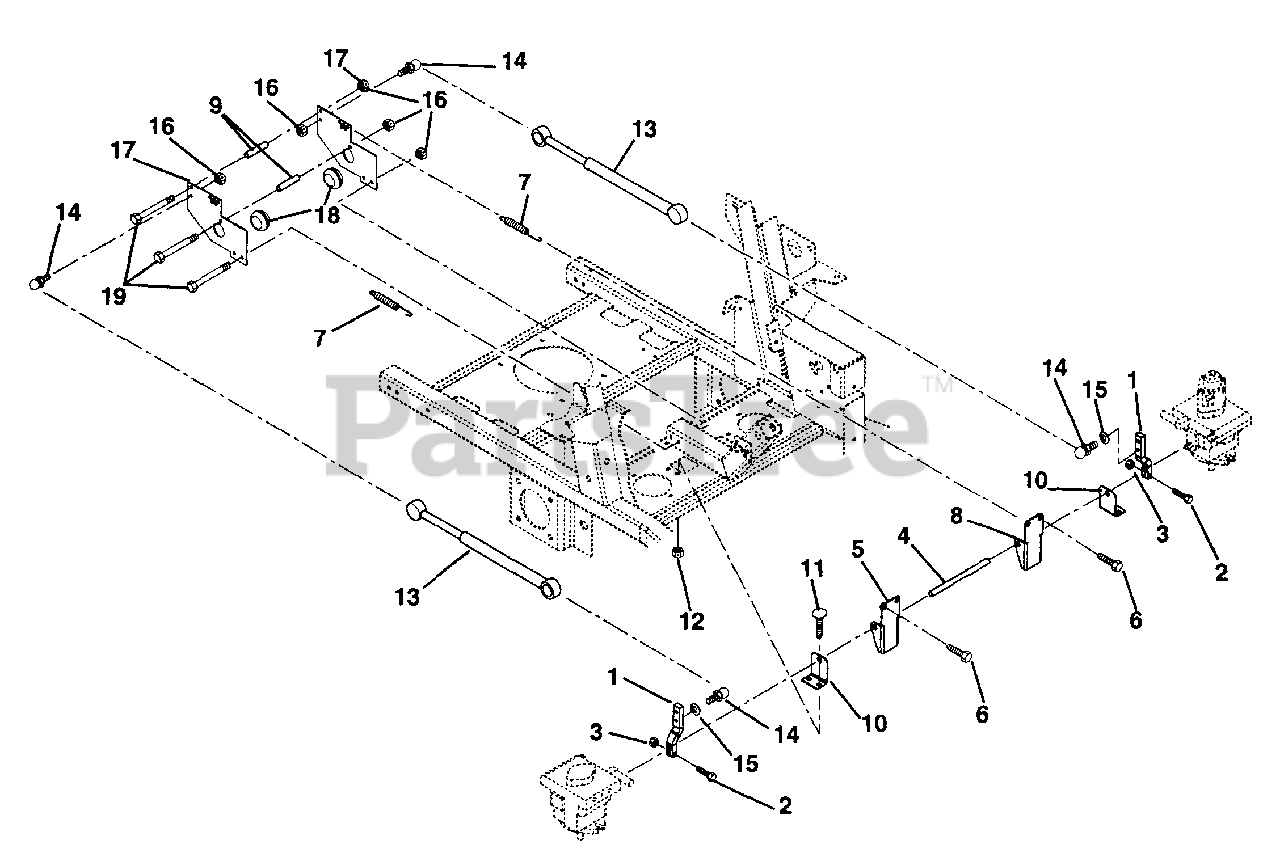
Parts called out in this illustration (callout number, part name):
1	ARM - PUMP ACTUATING
2	@BLT-HEX .25-20X1.25 GR5 YWZC
3	@NUT-LK-CTR .25-20 YWZC
4	ROD - PIVOT
5	PIVOT - NEUTRAL RH
6	@BLT-HEX .31-18X1.00 GR5 YWZC
7	SG-TENS .085X.60X5.13 WLD8.3
8	PIVOT - NEUTRAL LH
9	SPACER, .328 X .462 X 1.92 YWZ
10	SUPPORT - PIVOT ROD
11	@BLT-RDHDSQNK .31-18X.75 G5YZ
12	@NUT-LK-NYL .312-18 YWZC
13	DAMPENER CONTROL
14	STUD- BALL
15	@WSHR-LK .31X.078 REG YWZC
16	@NUT-LK-CTR .31-18 YWZC
17	ANCHOR, DAMPER
18	GROMMET 1.0ID X 1.38 OD
19	@BLT-HEX .31-18X2.75 GR5 YWZC
